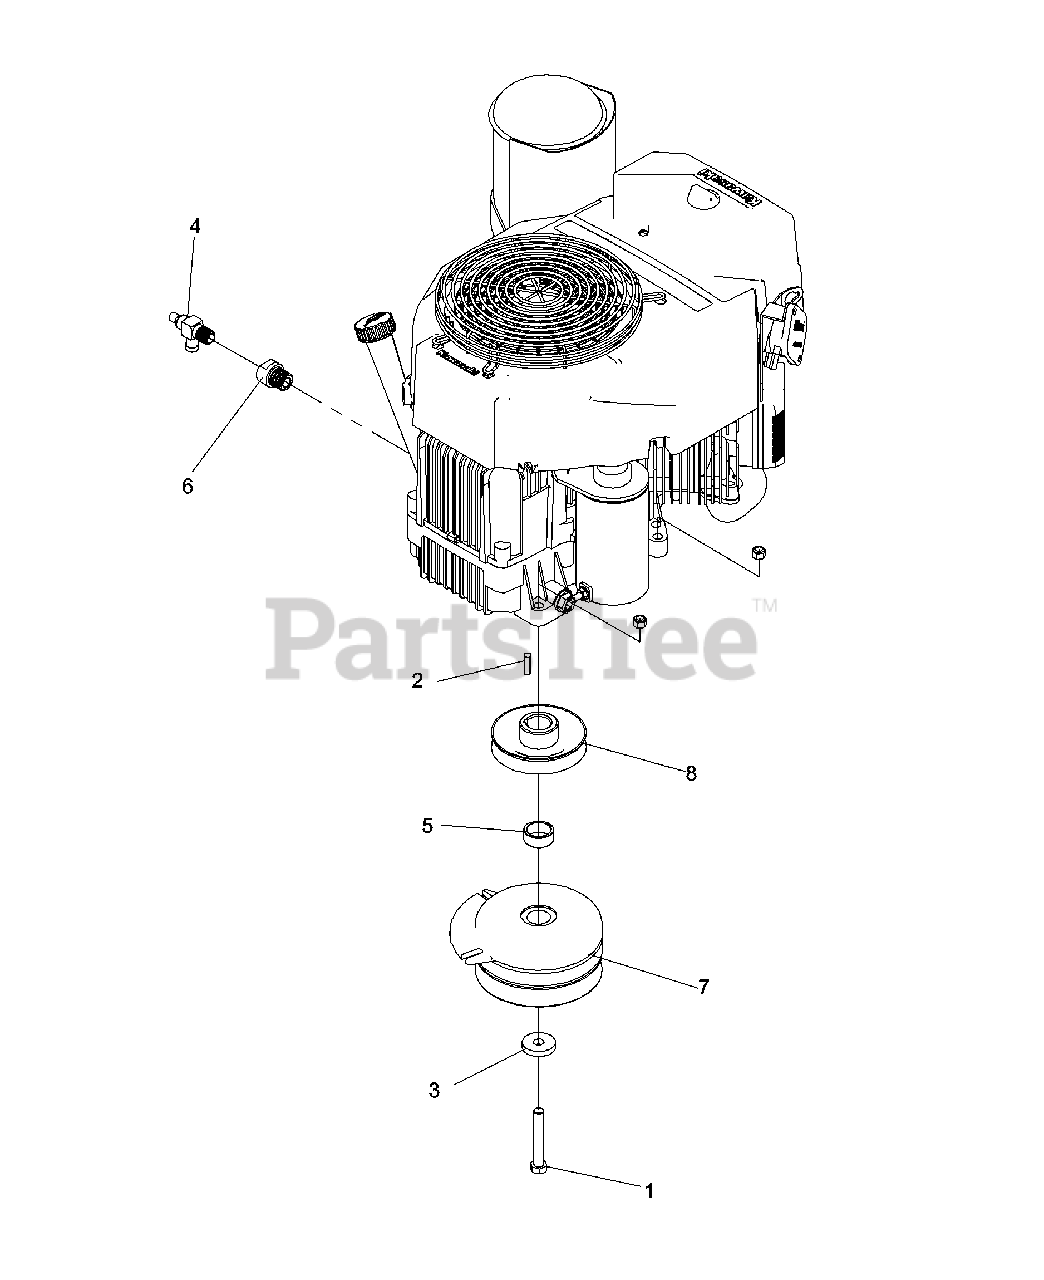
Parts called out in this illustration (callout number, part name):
1	HCS 7/16-20 X 2-3/4
2	KEY - 1/4 X .88
3	WASHER .43X1.38X.25
4	OIL DRAIN
5	HUB BEARING SPACER
6	ADAPTER, OIL DRAIN
8	DRIVE PULLEY-ENGINE
